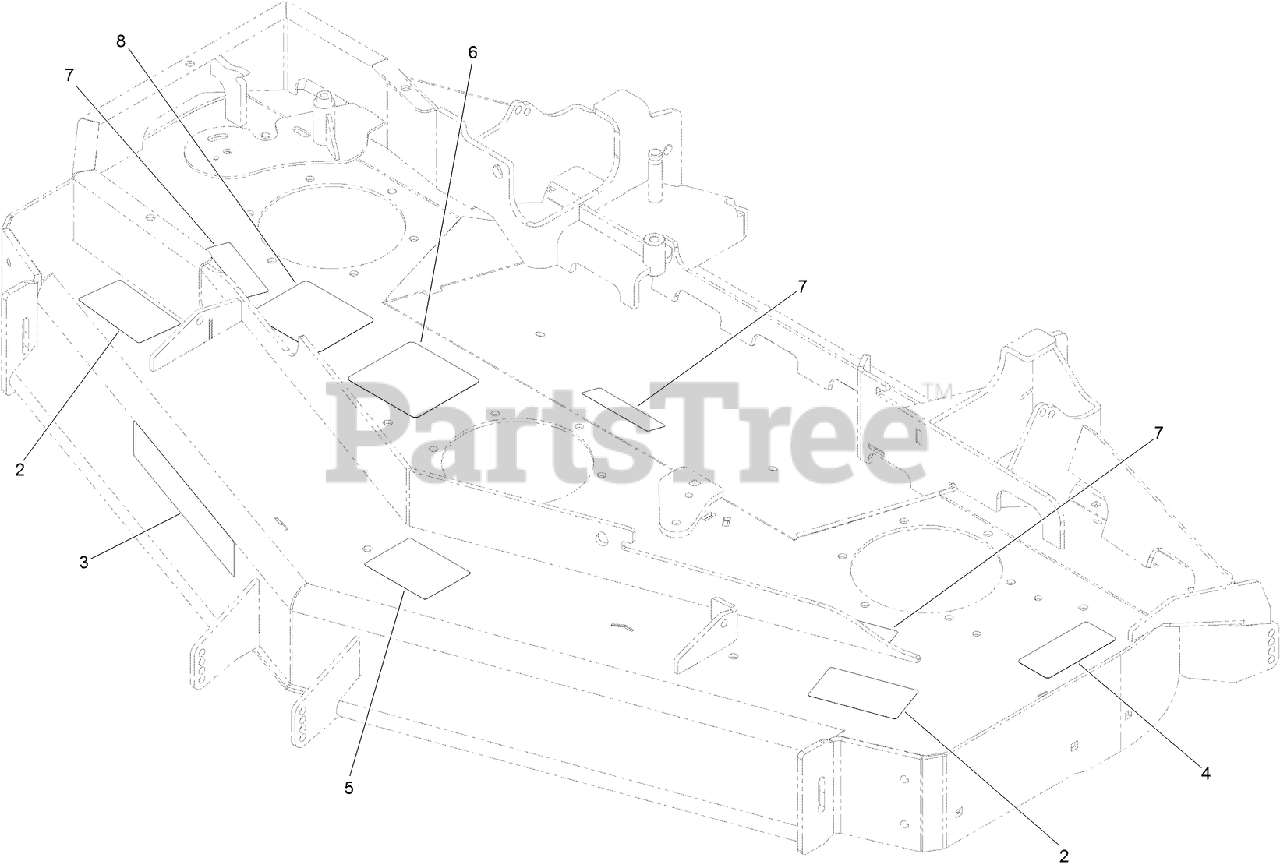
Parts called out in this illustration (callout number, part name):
2	DECAL-DANGER
4	DECAL-TORQUE, BLADE BOLT
5	DECAL-ANTI SCALP
6	DECAL-ROUTING, DECK BELT
7	DECAL-MISSING, COVER
8	DECAL-SPINDLE, COUNTER ROTATING
